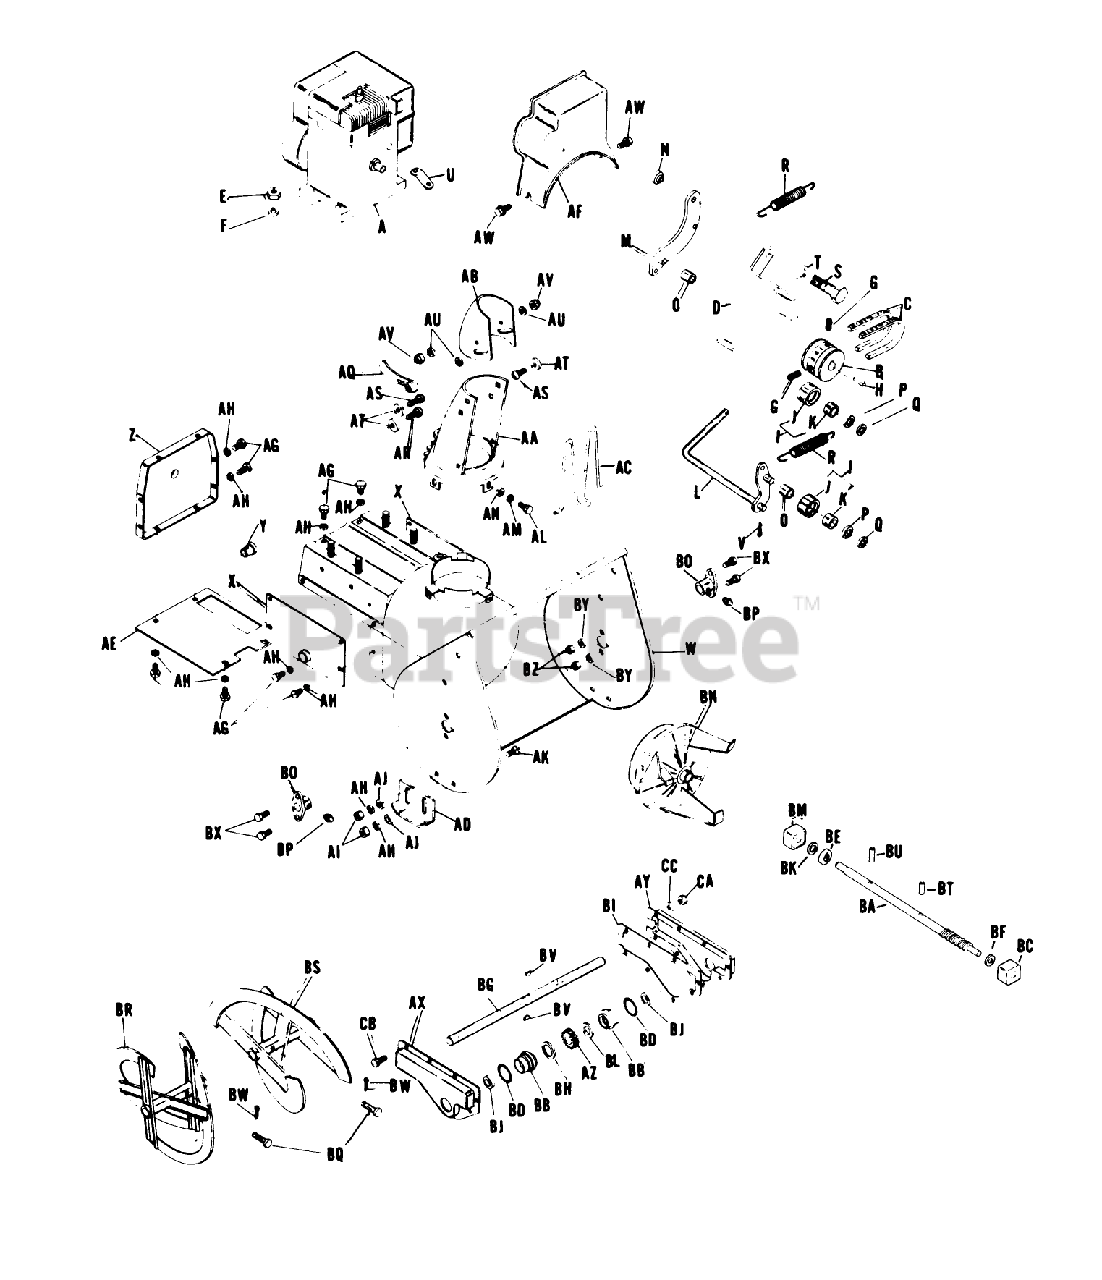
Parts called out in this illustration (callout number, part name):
A	Engine, 4 HP. BS Model 100202, Type 0434-01
D	Belt Guide
E	5/16-18 Hex. Nut, Plated
F	5/16 Spring Lock Washer, Plated
G	5/16-18 x 5/16 Socket Set Screw
H	3/16 x 3/16 x 1 1/4 Key
S	1/2-20 x 1 1/4 Hex. Hd. Cap Screw, Plated
T	1/2 Spring Lock Washer, Pl.
V	1/8 x 3/4 Cotter Pin, Plated
W	Auger Wrap Main Frame Assembly
Z	Backing Plate Assembly
AA	Chute Ring Assembly
AG	5/16-18 x 1/2 Hex. Hd. Cap Screw, Pl.
AH	5/16 Spring Lock Washer, Pl.
AI	5/16-18 Hex. Nut, Plated
AJ	5/16 Flat Washer, Plated
AK	5/16-18 x 3/4 Carriage Bolt, Plated
AL	1/4-20 x 3/4 Hex. Hd. Cap Screw, Plated
AM	1/4 Spring Lock Washer, Pl.
AN	1/4 SAE Flat Washer, Plated
AS	3/8-16 x 3/4 Carriage Bolt, Pl.
AT	1/2 Flat Washer, Plated
AU	3/8 Flat Washer, Plated
AV	3/8-16 Cone Lock Nut, Pl.
BG	Output Shaft
BN	Impeller, Pulley Assembly
BR	Auger Assembly, R.H.
BS	Auger Assembly, L.H.
BT	1/4 x 1" Roll Pin
BU	1/4 x 1 1/4" Roll Pin, Plated
BV	1/8 x 1/2 Woodruff Key, Alloy H.T.
BW	3/32 x 3/4 Cotter Pin, Plated
BX	5/16-18 x 3/4 Hex. Hd. Cap Screw, Plated
BY	5/16 Spring Lock Washer, Pl.
BZ	5/16-18 Hex. Nut, Plated
CA	1/4-20 Hex. Nut
CB	1/4-20 x 1/2 Hex. Hd. Cap Screw
CC	1/4 Spring Lock Washer
